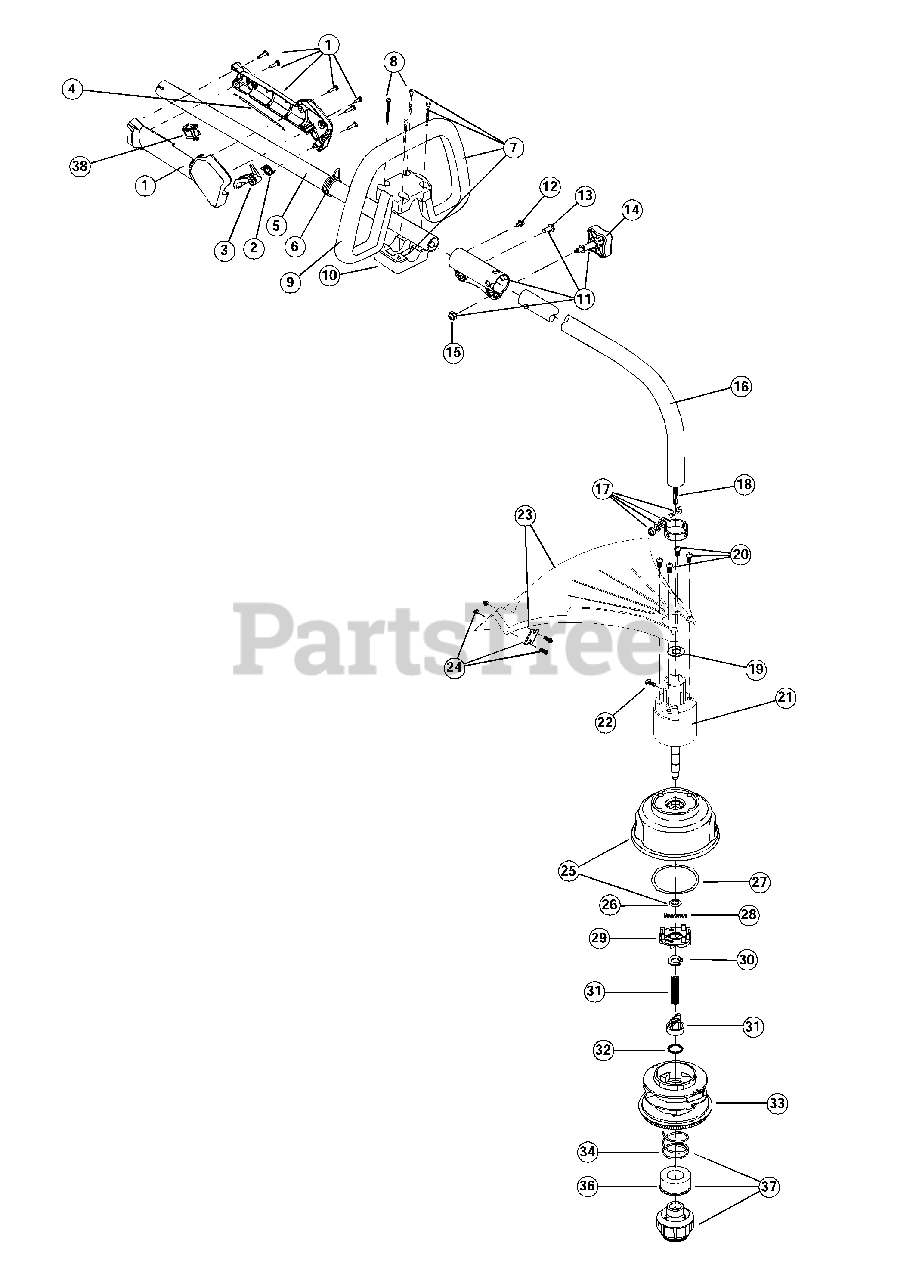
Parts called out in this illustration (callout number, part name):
1	Throttle Housing and Trigger Assembly
2	Throttle Trigger Spring
3	Throttle Trigger
4	Throttle Cable Assembly
5	Upper Drive Shaft Housing Assembly
6	Harness Clip
7	Deluxe D-Handle Assembly
9	Deluxe D-Handle
10	Bottom Clamp
11	EZ-Link Coupler
14	Adjustment Knob
15	Knob Retaining Nut
16	Lower Drive Shaft Housing Assembly
17	Lower Clamp Assembly
18	Lower Flexible Drive Shaft
19	Palnut
20	Shield Mounting Screw
21	Bushing Housing Assembly
22	Anti-Rotation Screw
23	Shield and Blade Assembly
24	Blade Assembly
25	Outer Spool and Eyelet Assembly
27	Thrust Washer
28	Small Spring
34	Inner Reel
35	Large Spring
37	Bump Head Knob Assembly w/Spring & Foam Seal
38	Switch Assembly
